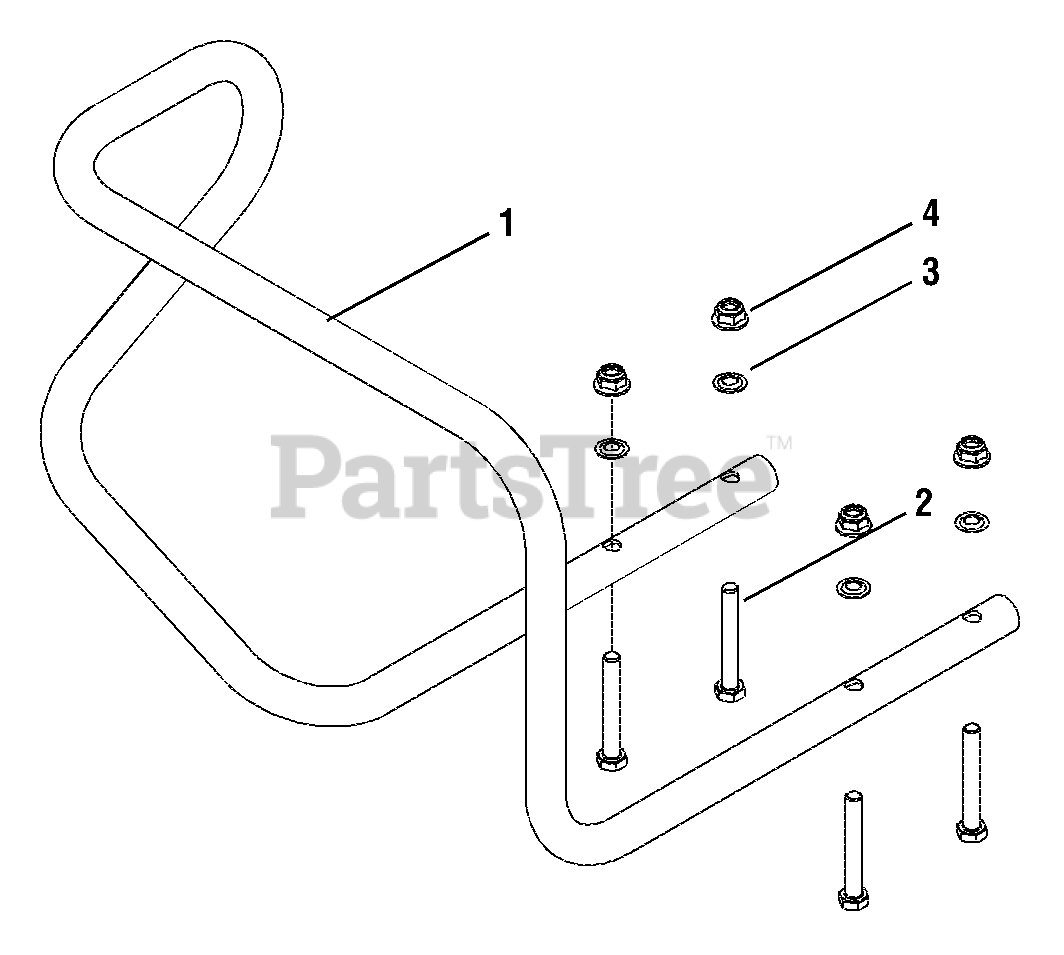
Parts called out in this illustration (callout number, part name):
2	Hex Screw, 5/16-18 x 2-1/4, Gr5
3	Nut, Speed, 5/16-18
4	Hex Lock Nut, Nylon, 5/16-18
